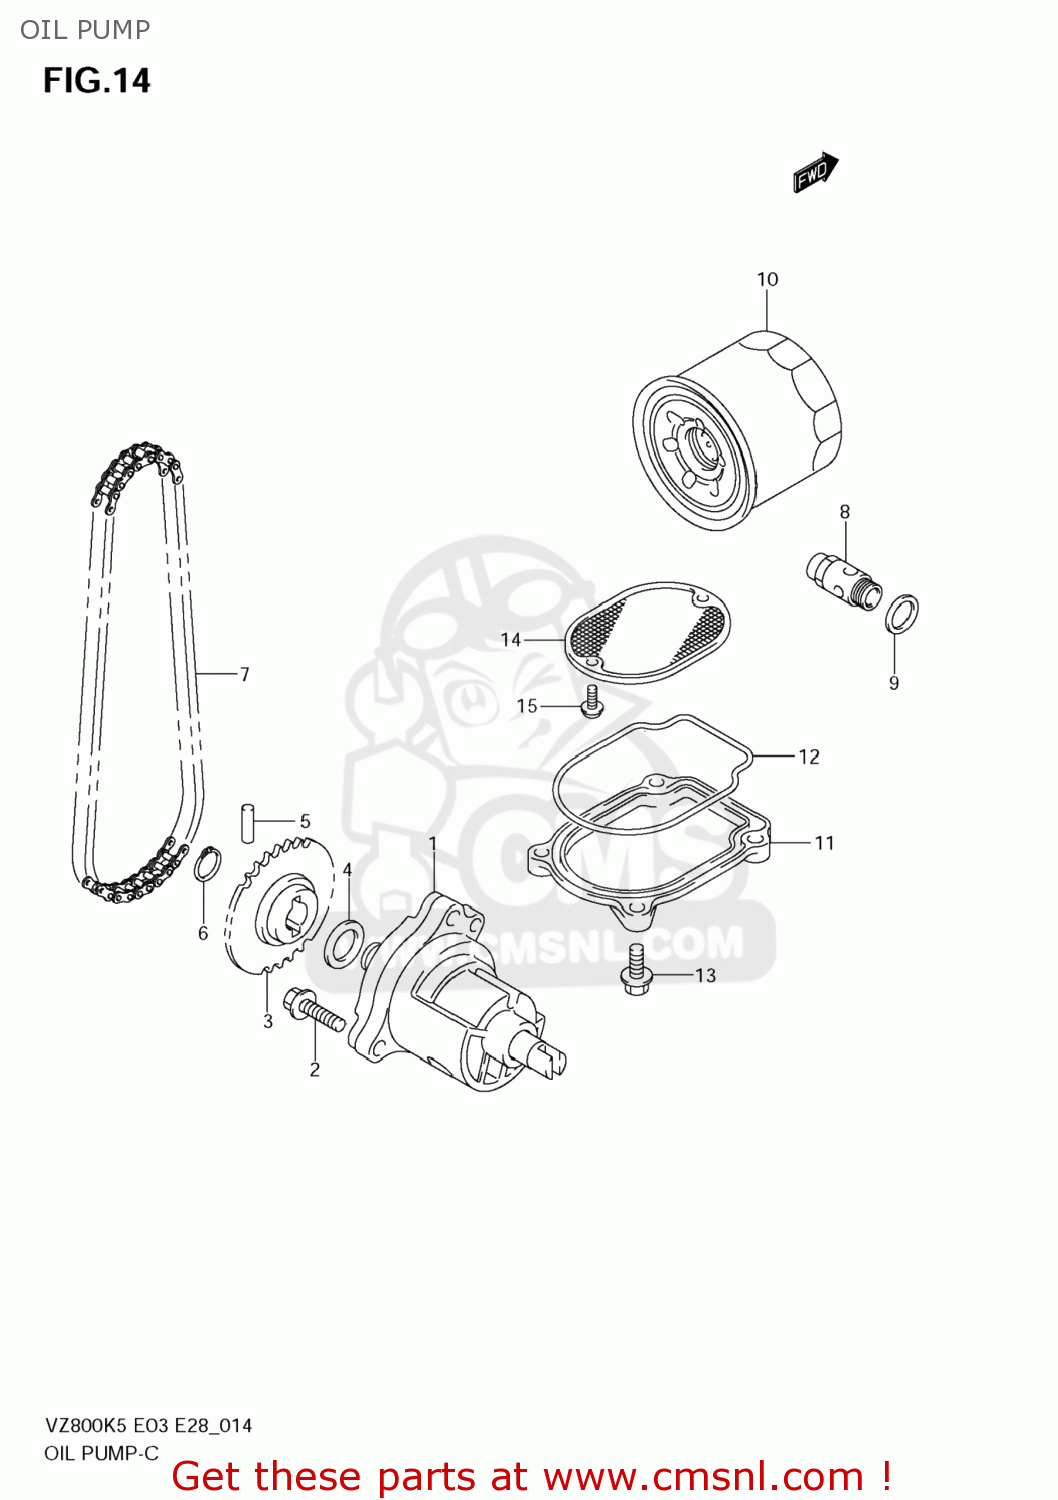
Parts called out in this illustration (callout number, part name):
1	PUMP ASSY,ENGINE OIL
2	BOLT
3	SPROCKET,OIL PUMP DRIVEN
4	SHIM(12X20X0.5)
5	PIN(5X18)
6	CIRCLIP
7	CHAIN,OIL PUMP DRIVE
8	VALVE ASSY,OIL RELIEF
9	GASKET(16X22X2) (NAS)
10	FILTER ASSY,EN
11	CAP,OIL STRAINER
12	O RING,OIL STRAINER CAP
13	BOLT
14	STRAINER,ENGINE OIL
15	SCREW
